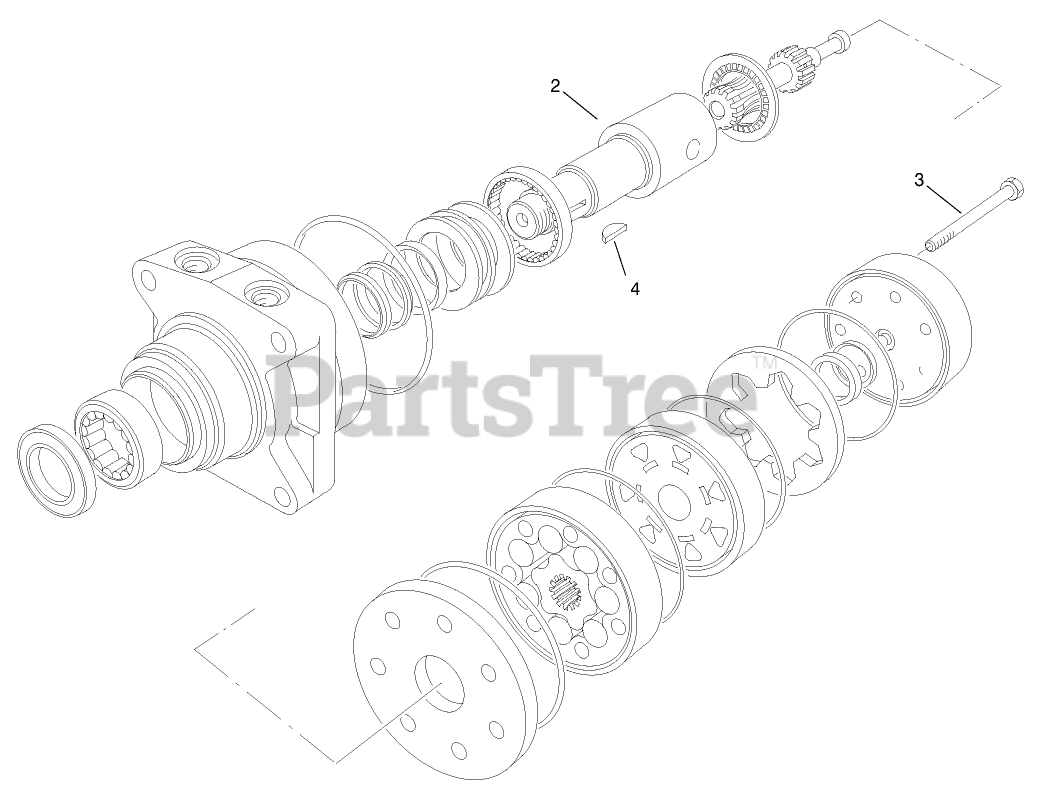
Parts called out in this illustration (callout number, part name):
2	SHAFT-COUPLING
3	SCREW-CAP, HH
4	KEY-WOODRUFF
